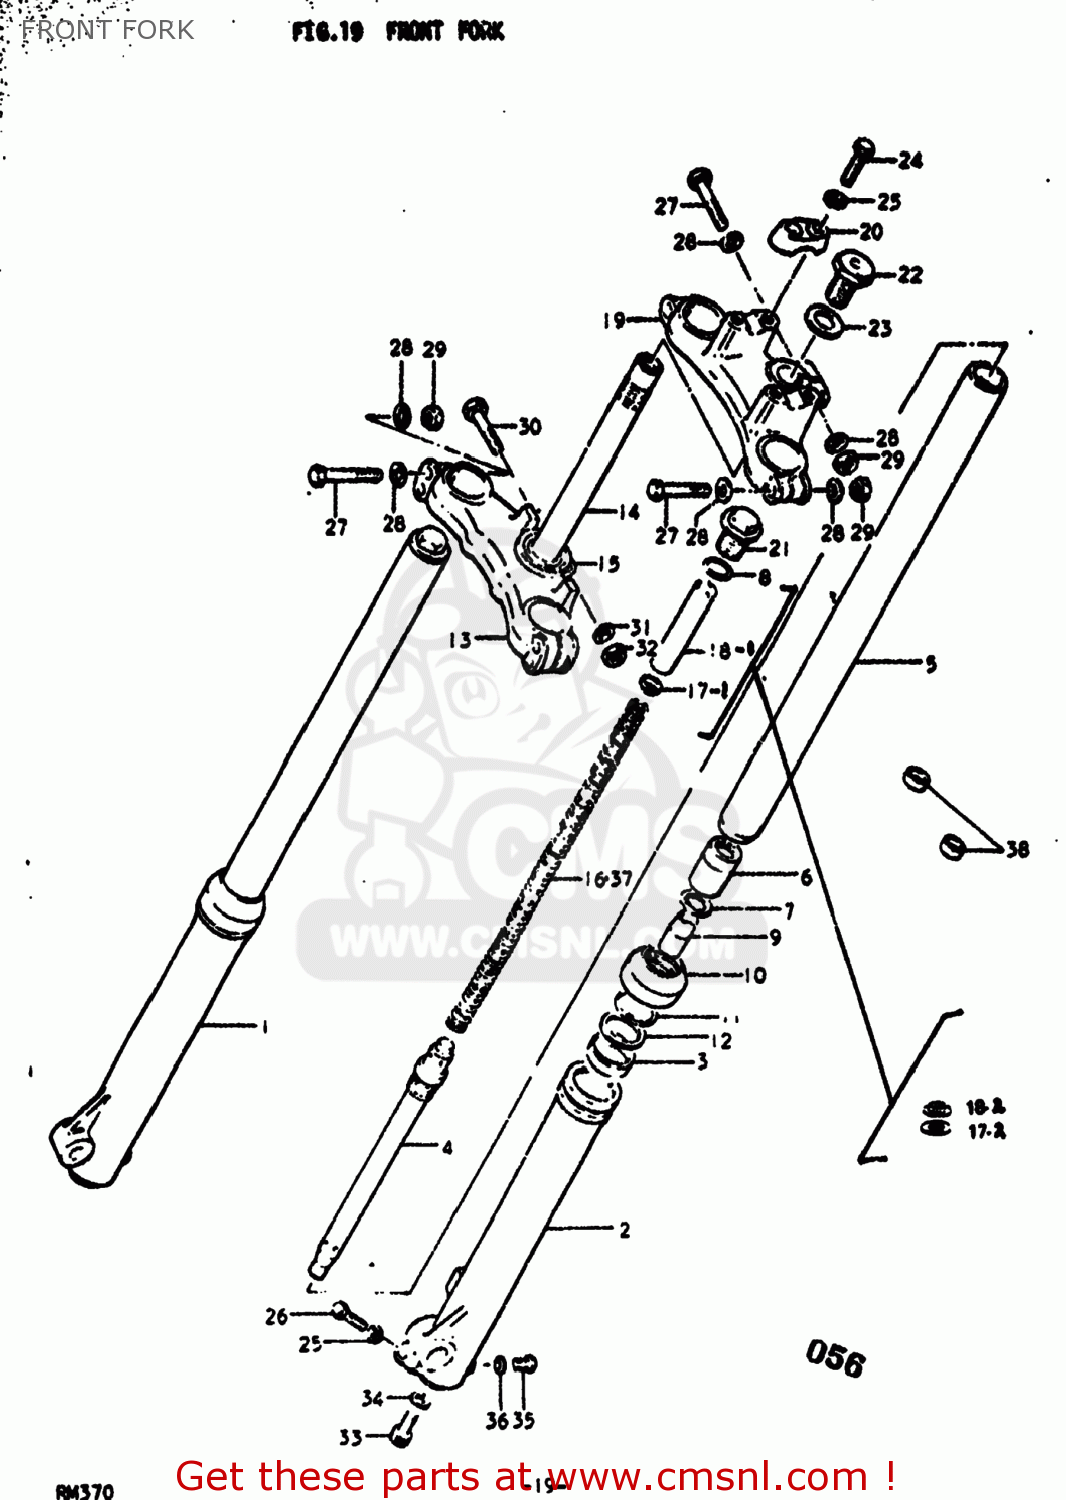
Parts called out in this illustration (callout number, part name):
0	DAMPER SET
1	TUBE,OUTER,RIGHT
2	TUBE,OUTER,LEFT
3	OIL SEAL,FRONT FORK
4	CYLINDER,FRONT FORK
5	TUBE,FORK,INNER
6	PISTON,FORK INNER TUBE
7	RING
8	O RING
9	PIECE,OIL LOCK
10	SEAL,DUST
11	CIRCLIP,FORK OIL SEAL
12	RING,FORK BACK UP
13	STEM,STEERING
14	STEM,STEERING
15	RACE,STEERING OUTER LWR
16	SPRING
17	GUIDE,FRONT FORK SPRING C
18	SPACER,SPRING
19	HEAD,STEERING STEM
20	HOLDER,HANDLEBAR
21	BOLT,FORK
22	CAP
23	WASHER
24	Bolt
25	LOCK WASHER
26	BOLT
27	BOLT 8X55
28	WASHER
29	NUT
30	BOLT
31	LOCK WASHER
32	NUT
33	BOLT,FORK CYLINDER(10X25)
34	GASKET (NAS)
35	SCREW
36	GASKET,DRAIN,PLUG (NAS)
37	SPRING
